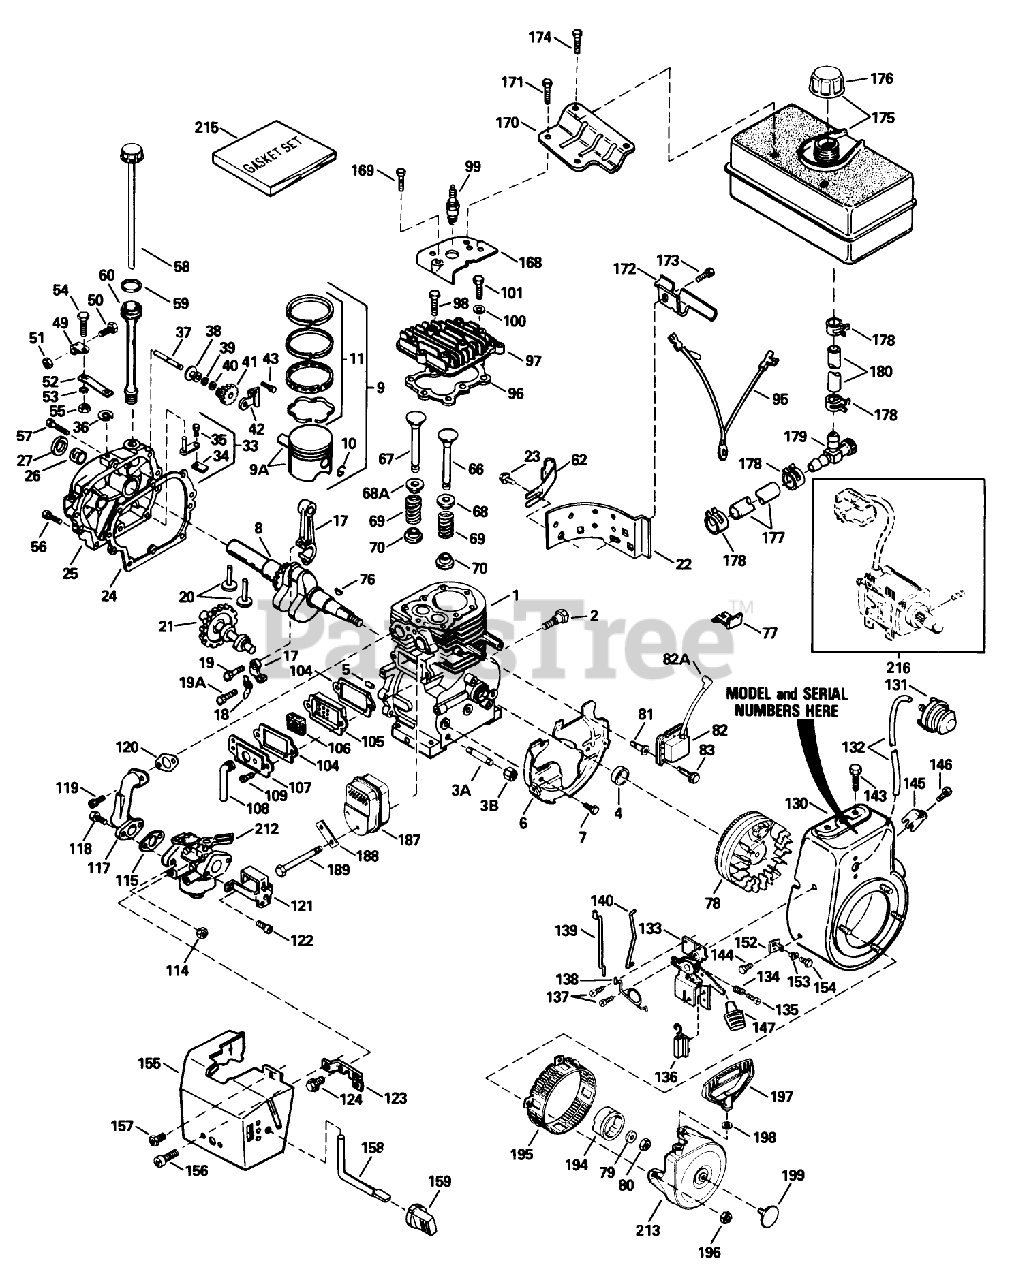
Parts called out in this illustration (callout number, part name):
1	Cylinder Asm (Includes 2, 20, 72)
2	Screw (1/4-20x1/2)
3A	Nipple-Pipe
3B	Cap-Pipe
4	Seal-Oil
5	Pin-Dowel
6	Baffle-Blower Housing
7	Screw (1/4-20x19/32)
8	Crankshaft
9	Piston, Pin Ring Assy.(Std.) (Incl. Ref. #24A, 25 26)
9A	Piston Pin Assy. (Std.) (Incl. Ref. #26)
11	Ring Set (Std.)
17	Rod Assy., Connecting (Incl. Ref. #28 28A)
18	Dipper-Oil
19	Bolt-Rod
19A	Bolt-Rod
20	Lifter-Valve
21	Camshaft (MCR)
22	Extension-Housing, Blower
23	Screw
24	Cylinder Cover Gasket
25	Cover-Cylinder (Includes 71, 75, 80)
26	2025A77 WIZARD ROTA
27	Seal-Oil
33	Rod, Governor (Incl. Nos.62 63)
34	Yoke-Governor
35	Screw (6-40x5/16)
36	Ring-Retaining
37	Shaft-Governor
38	Spool-Governor
39	Washer-Flat
40	Ring-Retaining
41	Gear Assy., Governor (Incl. Ref. #45)
42	Bracket-Gear, Governor
43	Screw (10-24x1/2)
49	Clamp-Lever, Governor
50	Screw
51	Nut-Lock
52	Lever-Governor
53	Washer-Lock
54	Screw
55	Nut-Lock
56	Screw (1/4-20x1-11/16)
57	Screw (1/4-20x1-3/16)
58	Dipstick
59	O-Ring
60	Tube-Fill, Oil
62	Clip-Tube, Fill
66	Valve, Exhaust (Standard)(Incl. No. 9)
67	Valve, Intake (Std.) (Incl. Ref. #58)
68	Cap-Spring, Valve
68A	Seal-Intake Valve
69	Spring-Valve
70	Keeper-Spring, Valve
76	Key-Flywheel
77	Clip-Wire
78	Flywheel (W/Ring Gear)
79	Washer-Belleville
80	Nut-Flywheel
82	Solid State ASM
82A	Cover-Spark Plug
83	Screw
95	Ground Wire
96	Gasket-Cylinder Head
97	Head Cylinder
98	Screw (5/16-18x1-1/2)
99	Spark Plug-Resistor (R J19 L M)
100	Washer-Flat
101	Screw (5/16-18x1-25/32)
104	Gasket-Breather
105	Body-Breather
106	Element-Breather
107	Cover-Valve
108	Tube-Breather
109	Screw
114	Nut and Lock Washer (1/4-28)
115	Gasket-Carburetor To Intake Pipe
117	Pipe-Intake
118	Screw (1/4-28x1)
119	Screw (T-30, 5/16-18x1-3/32)
120	Gasket-Intake
121	Bracket-Choke
122	Screw (10-32 x 1/2)
123	Bracket-Carburetor
124	Screw (8-32x27/64)
130	Housing-Blower
131	Primer-Asm
132	Line-Primer
133	Control Assy., Remote Speed (Incl. Ref. #90 thru 93)
134	Spring-Compression
135	Screw
136	Terminal
137	Screw (10-32 x 1/2)
138	Spring-Throttle
139	Link-Governor
140	Link-Throttle
143	Screw (5/16-18x3/4)
144	Screw
145	Screw
146	Screw (8-32 x 3/8)
147	Knob-Control
152	Bracket
153	Grommet
154	Screw (8-32 x 3/8)
155	Cover-Carburetor
156	Screw (10-32 x 3/8)
157	Screw (10-32x1/2)
158	Rod-Choke
159	Knob-Control
168	Cover-Cylinder Head
169	Screw (1/2-20x5/8)
170	Bracket-Tank, Fuel (Black)
171	Screw
172	Bracket-Tank, Fuel
173	Screw (1/4-20x19/32)
174	Screw (1/4-15x7/8)
175	Tank-Fuel (Includes 292, 301)
176	Cap-Fuel
177	Line-Fuel
178	Clamp-Line, Fuel
179	Valve-Shut Off
180	Line-Fuel (8.62)
187	Muffler
188	62513 SNWTHWR W/284
189	Screw
194	Cup-Starter
195	Screen-Starter
196	Nut and Lock Washer (1/4-28)
197	Handle-Starter, Mitten Grip
198	Washer
199	Plug Starter
212	Carburetor (Incl. Ref. #75)
213	Starter-Rewind
215	Gasket Set (Incl. items marked *) Order As Accessory.
